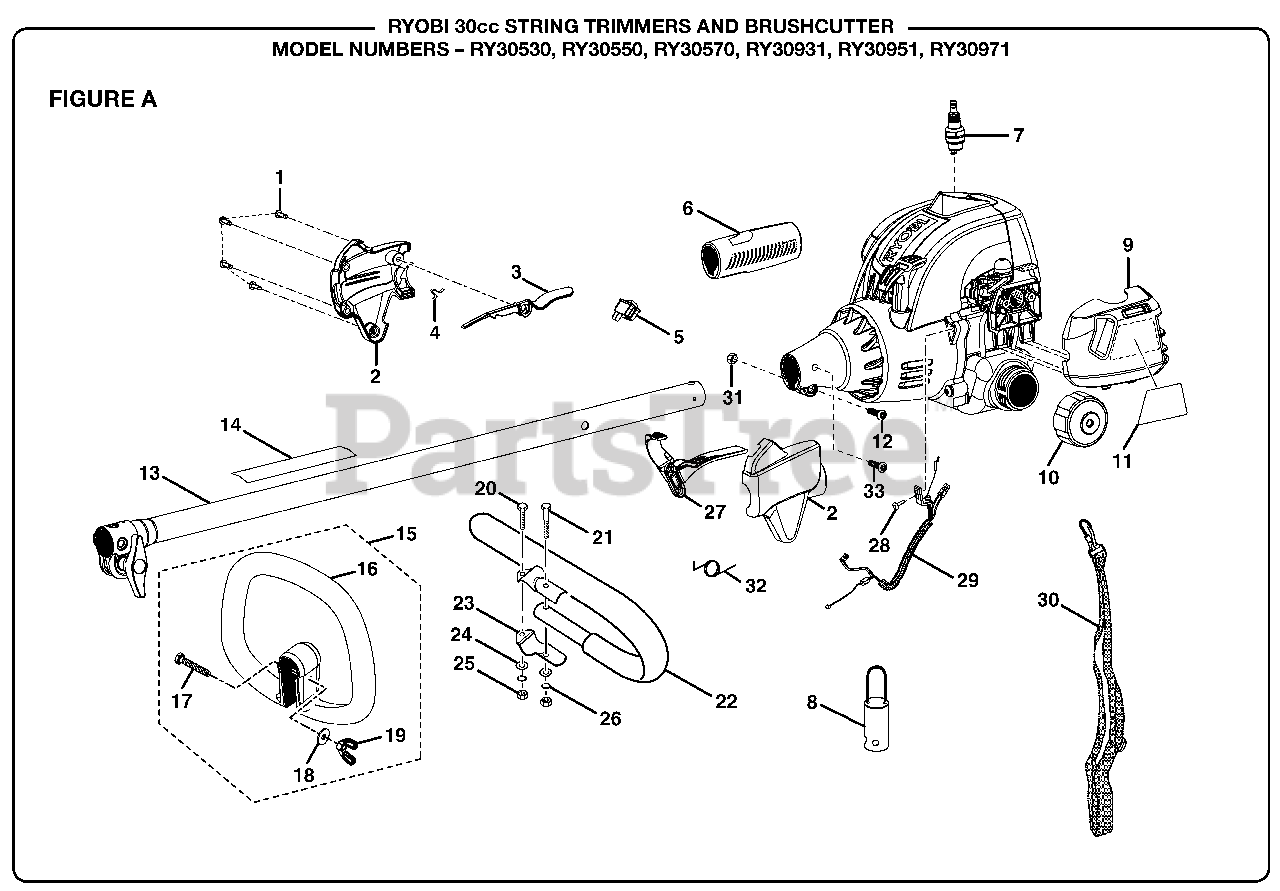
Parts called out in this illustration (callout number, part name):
1	Screw
2	Control Handle Assembly
3	Trigger Lock
4	Strap Hanger
5	Switch
6	Rear Handle
7	Spark Plug
8	Hanger Cap
9	Air Box Cover
10	Fuel Cap Assembly
11	Label
12	Bolt
13	Upper Boom Assembly
14	Warning Decal
15	Front Handle Assembly
16	Front Handle
17	Bolt
18	Flat Washer
19	Wing Nut
20	Bolt
21	Bolt
22	“J” Handle and Grip
23	Handle Bar Clamp
24	Washer
25	Hex Nut
26	Lock Washer
27	Throttle Trigger
28	Screw
29	Throttle and Lead Assembly
30	Shoulder Harness
31	Hex Nut
33	Screw
